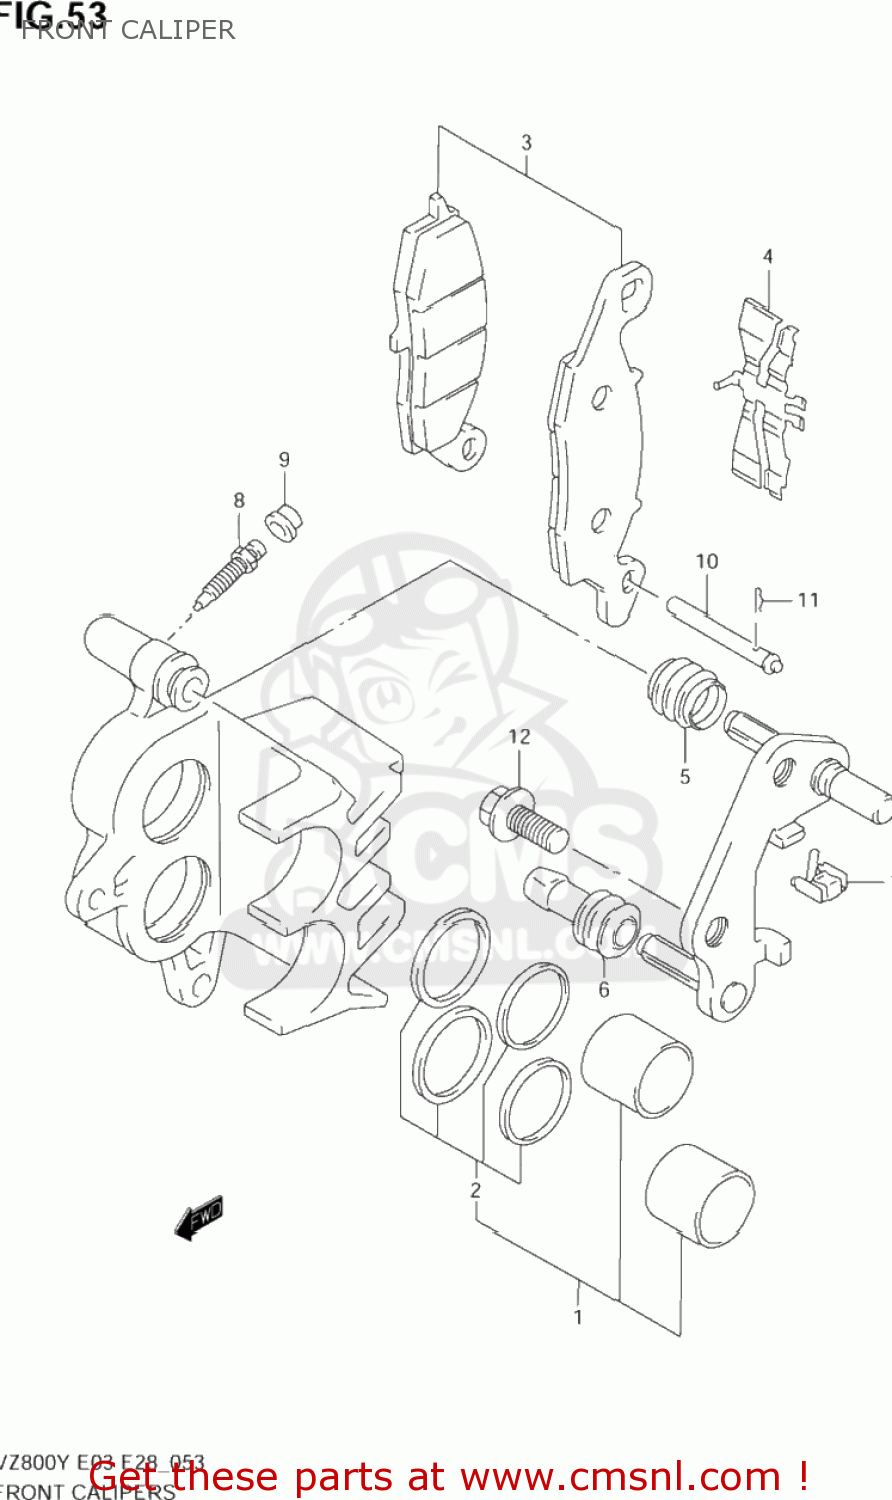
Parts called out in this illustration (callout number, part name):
1	PISTON SET
2	SEAL SET,PISTO
3	PAD SET (NAS)
4	SPRING,PAD,R
5	BOOT,AXLE
6	INSULATOR,AXLE
7	GUIDE,PAD
8	BLEEDER
9	CAP,BLEEDER PLUG
10	PIN,PAD
11	CLIP,PAD PIN
12	BOLT
